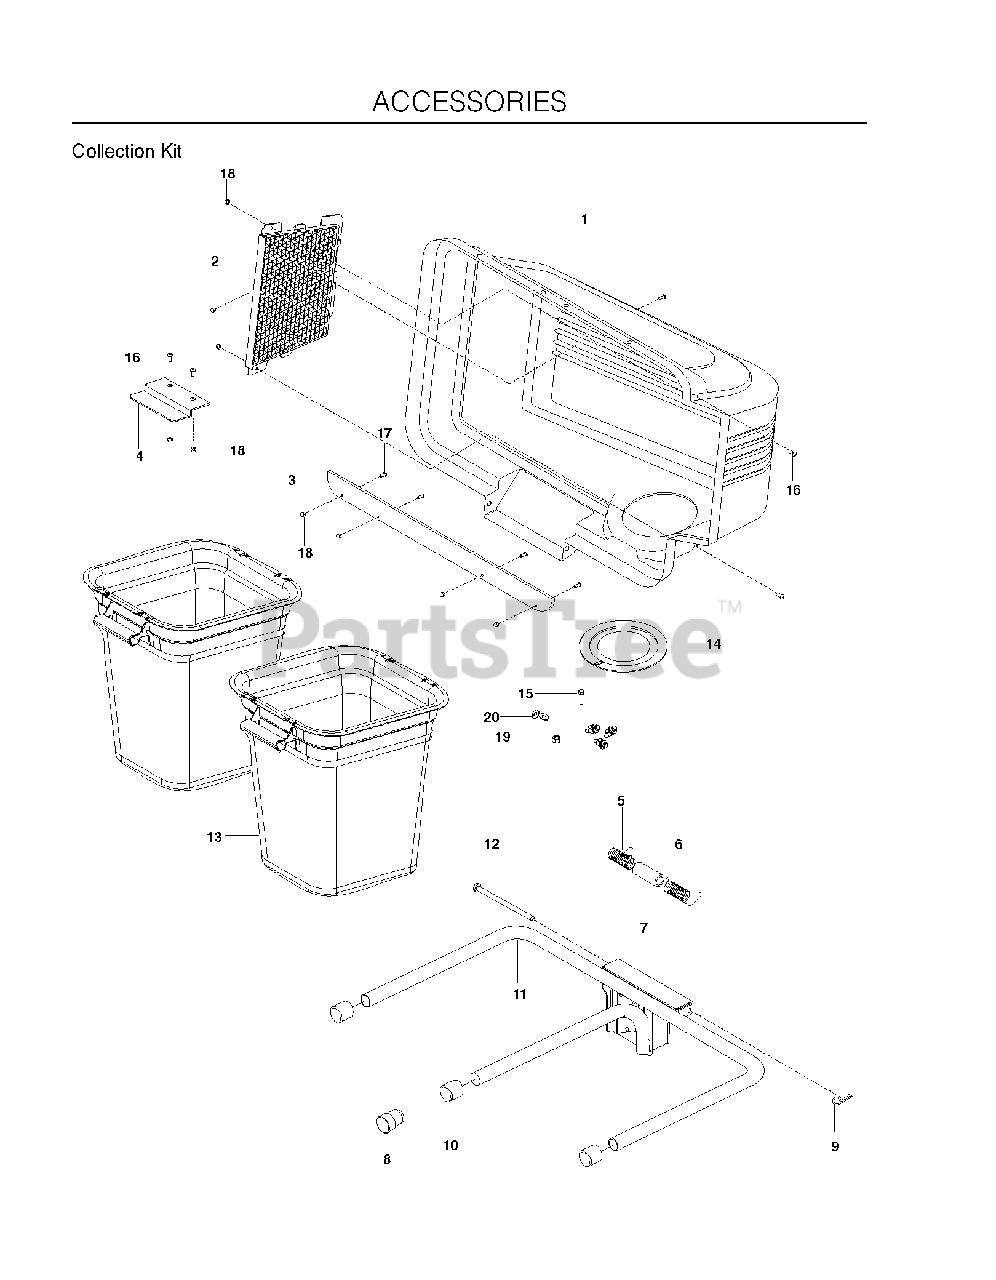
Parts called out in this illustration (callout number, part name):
1	COVER ASSY, COMP
2	COVER SCREEN
3	STRIP, REINFORCEMENT
5	SPRING COVER LH
6	SPRING COVER RH
7	SPACER COVER
8	SPACER PLUG, BAGGER
9	RETAINER SPRING
10	PLUG, TUBING
11	FRAME ASSEMBLY, 2 BIN
12	HINGE PIN
13	CONTAINER BAG, SOFT
14	COVER GASKET
15	SCREW 10-24 X 3/4
16	SCREW #10-24 X 5/8
17	SCREW
19	NUT 10-24 NYLOC
20	WASHER #10
